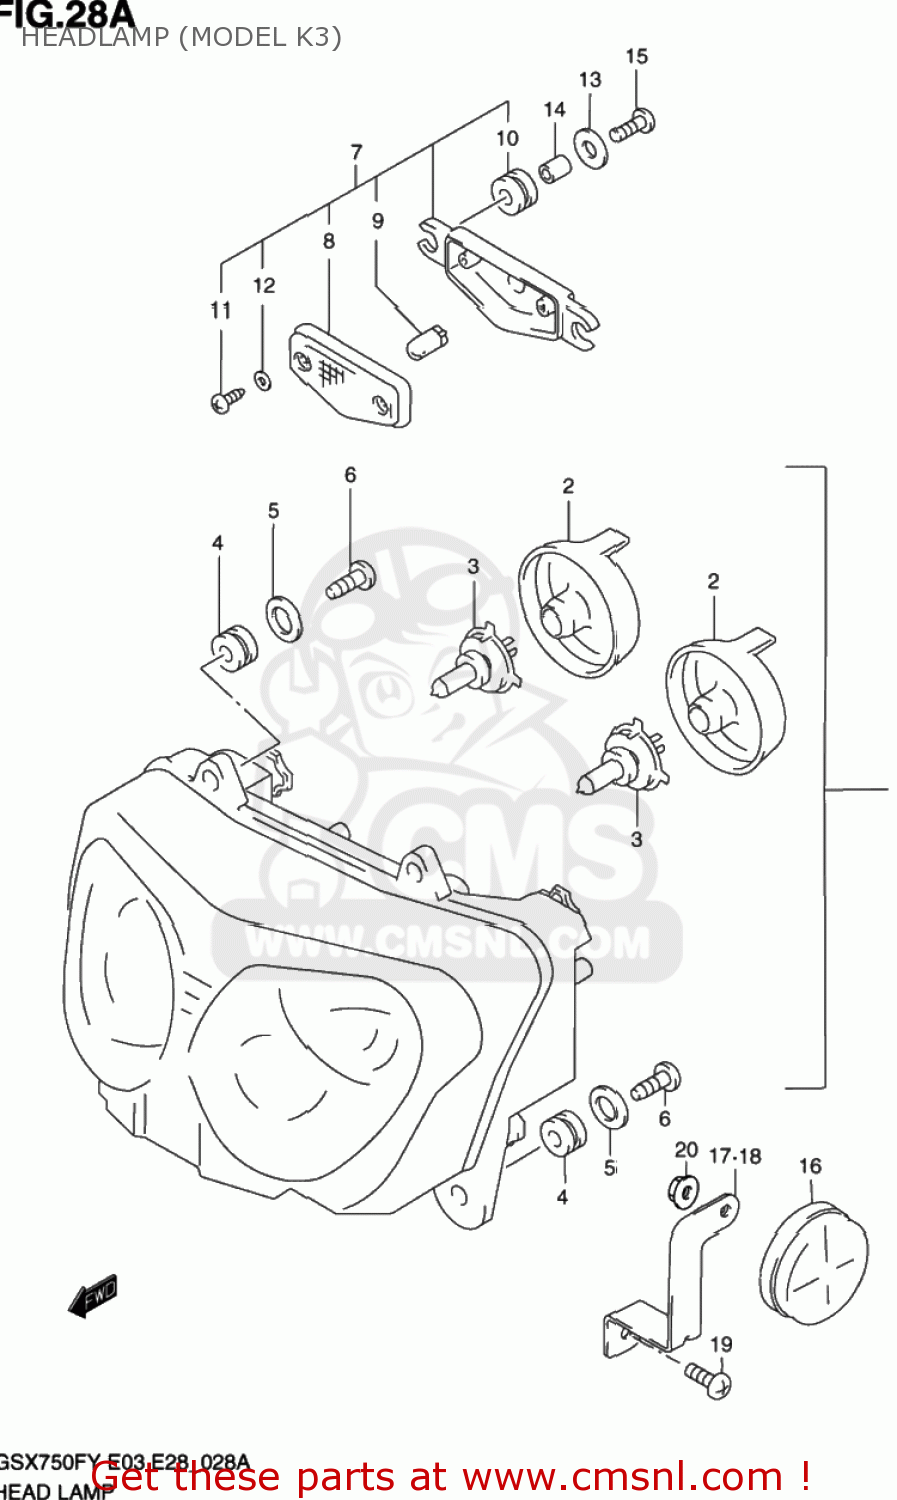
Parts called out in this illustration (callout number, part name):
1	HEADLAMP ASSY
2	COVER,SOCKET
3	BULB(12V60/55W,H4)
4	CUSHION,HEADLAMP
5	WASHER(5.5X18X1)
6	SCREW
7	LAMP ASSY,FR POSITION
8	LENS
9	BULB(12V5W)
10	CUSHION
11	SCREW
12	WASHER
13	WASHER(5.5X18X1)
14	SPACER(5.5X8X10.5)
15	SCREW 5X20
16	REFLECTOR,REFLEX FR
17	BRACKET,FR SIDE
18	BRACKET,FR SIDE RR,L
19	SCREW
20	NUT
